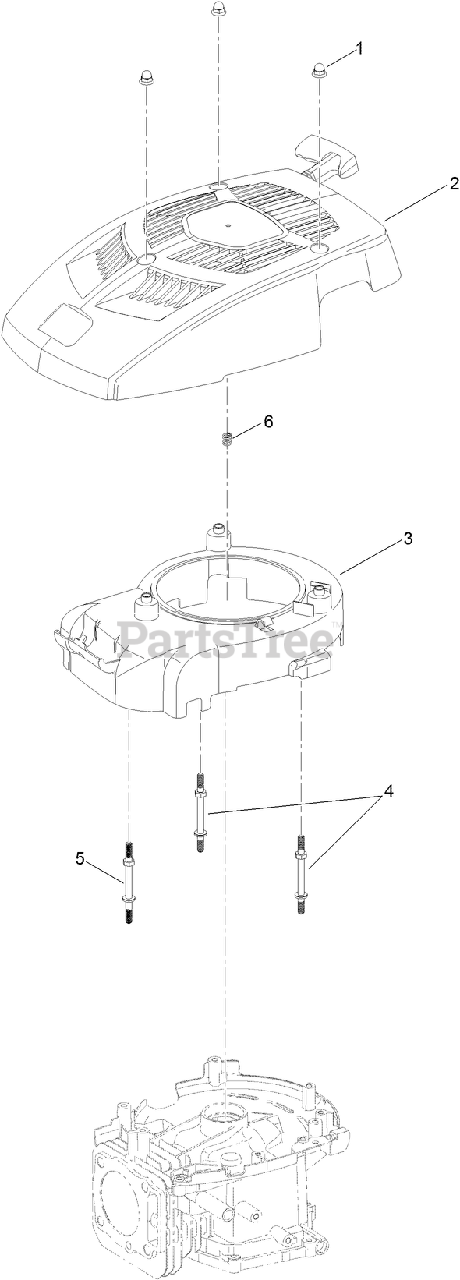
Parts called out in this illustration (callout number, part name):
1	NUT-ACORN
2	RECOIL SHROUD ASM
3	SHROUD-FAN
4	STUD-SHROUD
5	STUD-SHROUD
6	SPRING-COMPRESSION, RECOIL
